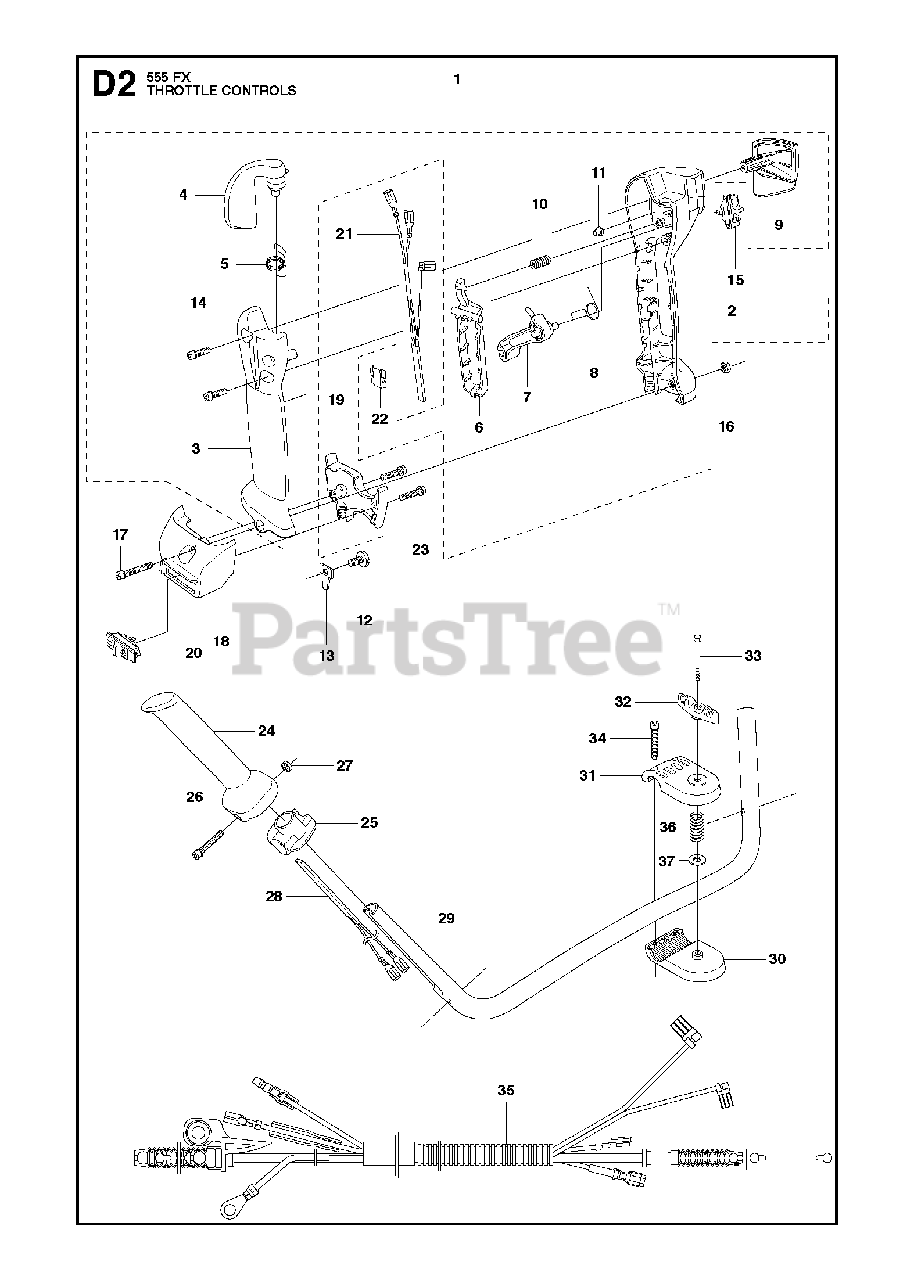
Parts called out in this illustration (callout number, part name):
1	THROTTLE HANDLE
2	HANDLE
3	HANDLE
4	THROTTLE TRIGGER
5	RP SPRING
6	THROTTLE LOCK
7	LEVER
8	SPRING
9	COVER
10	SPRING
11	SLEEVE
12	SCREW
13	HOLDER
14	SCREW
15	STOP BUTTON
16	NUT M6M M5
17	SCREW
18	HOLDER
19	HOLDER
20	SWITCH (G)
21	HEATING ELEMENT
23	SCREW
27	NUT M6M M5
28	HEATING ELEMENT
29	%HANDLE
30	HANDLE HOLDER LOWER
31	HANDLE HOLDER UPPER
35	WIRING
